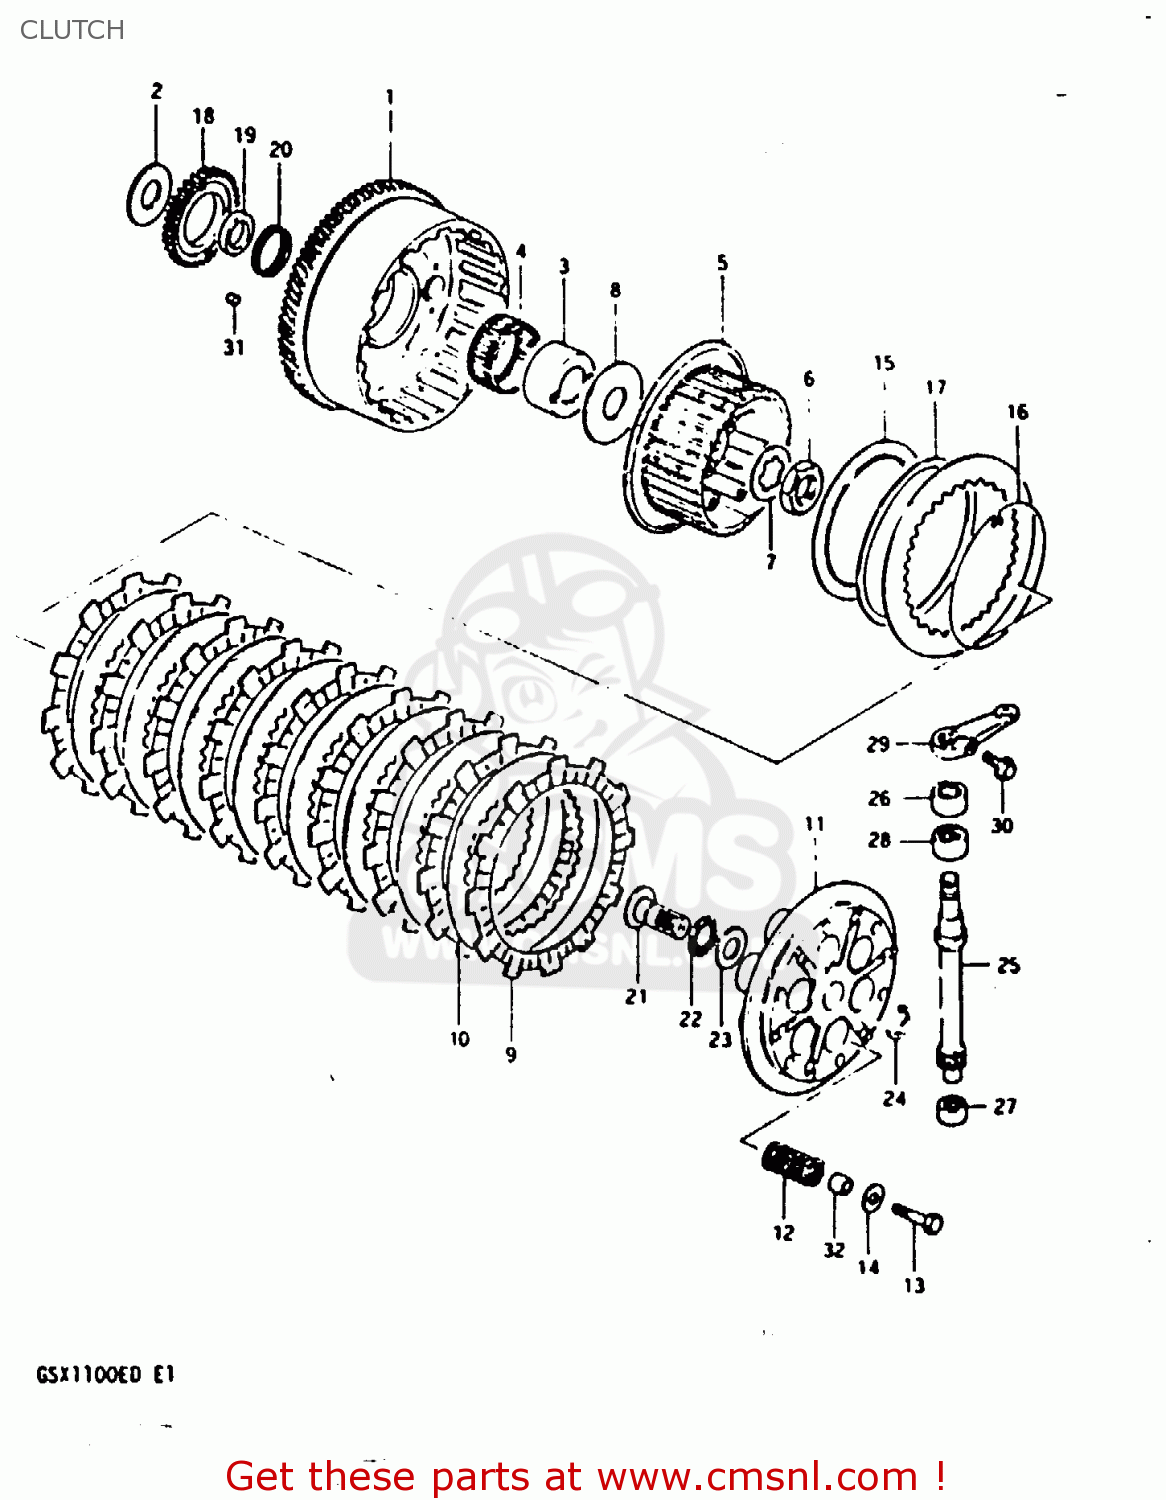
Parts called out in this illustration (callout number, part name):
1	GEAR ASSEMBLY,PRIMARY DRIVE
2	WASHER
3	SPACER
4	BEARING
5	HUB,CLUTCH SLEEVE
6	NUT
7	WASHER,LOCK
8	WASHER(25X66X3.5)
9	PLATE,CLUTCH DRIVE (MCA)
10	PLATE,CLUTCH DRIVEN (NAS)
11	DISC,CLUTCH PRESSURE
12	SPRING
13	BOLT
14	WASHER
15	SEAT,WAVE WASHER
16	RING,STOPPER
17	WASHER
18	GEAR,ENG OIL PUMP DRIVE(NT:34)
19	SPACER,OIL PUMP DRIVE GEAR
20	BEARING(36X40X10)
21	RACK,CLUTCH RELEASE
22	BEARING(15X28X2)
23	WASHER
24	E RING 12MM
25	PINION,CLUTCH RELEASE
26	OIL SEAL
27	BEARING(12X19X12)
28	BEARING(15X22X12)
29	ARM,CLUTCH RELEASE
30	BOLT (6X20)
31	CUSHION,PRIMARY DRIVEN GEAR
32	SPACER
